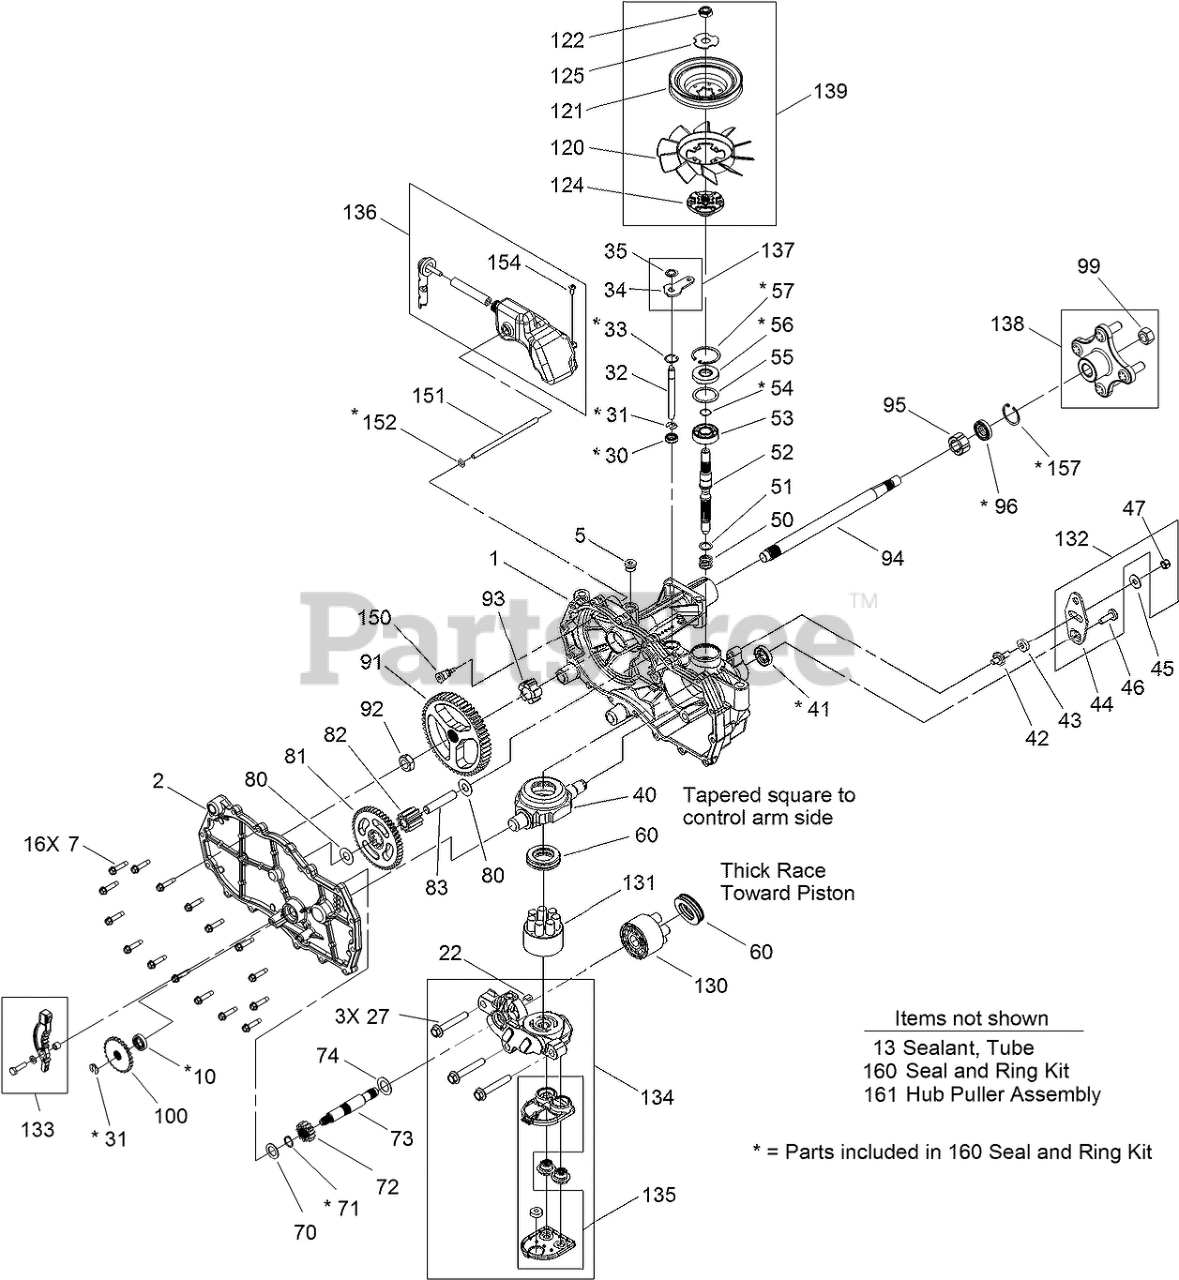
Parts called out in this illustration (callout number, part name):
1	MAIN HOUSING ASM
2	HOUSING SIDE KIT
5	PLUG-THREAD, STRAIGHT
7	SCREW-HHF
10	SEAL-LIP
22	PLATE-BYPASS
27	BOLT-HEX FLANGE
30	SEAL-LIP
31	RING-RETAINING, EXTERNAL
32	ROD-BYPASS
33	RING-RETAINING, INTERNAL
34	ARM-BYPASS
35	RING-RETAINING, EXTERNAL
40	SWASHPLATE-TRUNNION
41	SEAL-LIP
43	PUCK-FRICTION
44	ARM-CONTROL
45	WASHER
50	SPRING-COMPRESSION
51	WASHER
52	SHAFT-INPUT
53	BEARING-BALL
54	RING-RETAINING
55	SPACER
56	SEAL-LIP
57	RING-RETAINING
60	BEARING-THRUST
70	WASHER-FLAT
71	RING-RETAINING
72	GEAR-PINNION, 13T
73	SHAFT-MOTOR
74	WASHER
80	WASHER
81	GEAR-10T/48T
82	GEAR-JACKSHAFT, 10T
83	PIN-JACKSHAFT
91	GEAR-BULL
92	NUT-HJ
93	BUSHING-INBOARD
94	SHAFT-AXLE
95	BEARING-SLEEVE
96	SEAL-LIP
99	NUT-HEX LOCK
100	DISC-BRAKE, COG
120	FAN-6 INCH
121	PULLEY
122	NUT-LOCK
124	HUB
125	WASHER-SLOTTED
130	CYLINDER BLOCK KIT
131	PUMP BLOCK ASM
132	CONTROL ARM KIT
133	BRAKE ARM KIT
134	CENTER SECTION FILTER KIT
135	FILTER KIT
136	EXPANSION TANK KIT
137	BYPASS ARM KIT
138	HUB KIT
139	FAN PULLEY KIT
150	FITTING-SAE
152	O-RING
154	BOLT-SELF TAPPING
157	RING-RETAINING
